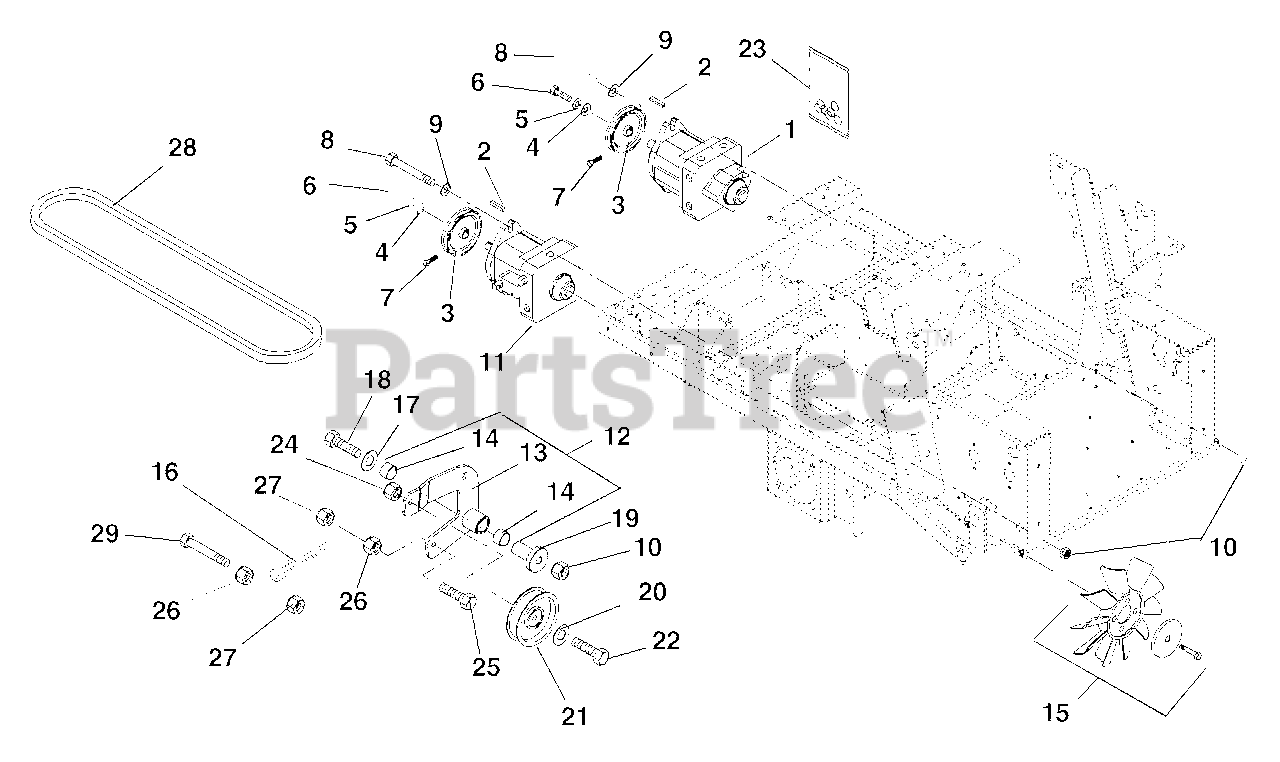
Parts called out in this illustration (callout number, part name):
1	PUMP, HYD. (RTN) W/AUX
2	KEY, SQ 5 X 5 X 30MM PLAIN
3	SHEAVE, POLY V .671 X 4.125
4	WSHR-FL-STL .281X1.000X.063
5	@WSHR-LK .25X.062 REG YWZC
6	BLT-HEX M6 X 1.0X12 YWZC
7	SCR-SKH .25-20 X .50 PH & OIL
8	@BLT-HEX .50-13X1.50 GR5 YWZC
9	@WSHR-FL-STL.531X1.06X.095YWZC
10	@NUT-LK-TOP-FLG .50-13 YWZC
11	PUMP, HYD. (RTN)
12	ASSEMBLY, IDLER ARM
13	WMT, IDLER ARM
14	BRG, 1.00 X 1.12 X .75
15	FAN, HYDRO PUMP COOLING
16	SG-TENS .135X.69X5.75 WLD 150
17	@WSHR-FL-STL.563X1.38X.109YWZC
18	@BLT-HEX .50-13X3.50 GR5 YWZC
19	BEARING, PEDESTAL
20	@WSHR-FL-STL.406X.812X.065 YWZ
21	IDLER, FLAT 4.00X1.06
22	BLT-HEX .38-16X1.625
23	KIT, PUMP SEAL (BDP-21L)
24	@NUT-LK-TOP-FLG .38-16 YWZC
25	@BLT-HEX .31-18X1.25 GR5 YWZC
26	@NUT-HEX .31-18 YWZC
27	@NUT-LK-TOP-FLG .31-18 YWZC
28	POLY V-BELT, K-5 RIBS
29	@BLT-HEX .31-18X2.50 GR5 YWZC
